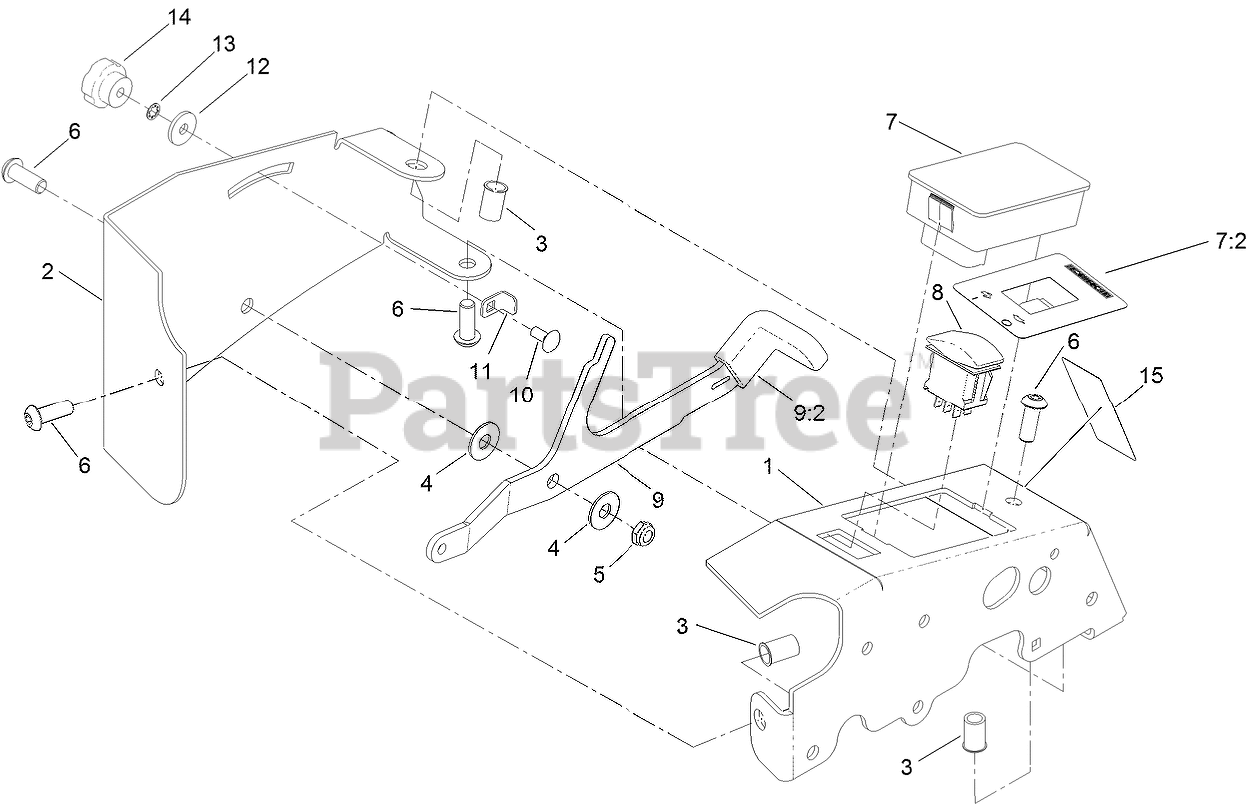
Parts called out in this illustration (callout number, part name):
1	BRACKET-MOUNT
2	COVER-CONTROLLER, SPREADE
3	NUT-CLINCH
6	SCREW-HSBH
7	Spreader Control Module ASM
7:2	DECAL-SPEED, IMPELLER
10	SCREW-CARR
11	BRACKET-GATE, SET
12	WASHER-FRICTION
13	WASHER-LOCK, INT
14	KNOB-CHUTE
15	DECAL-CONTROL, SPREAD
